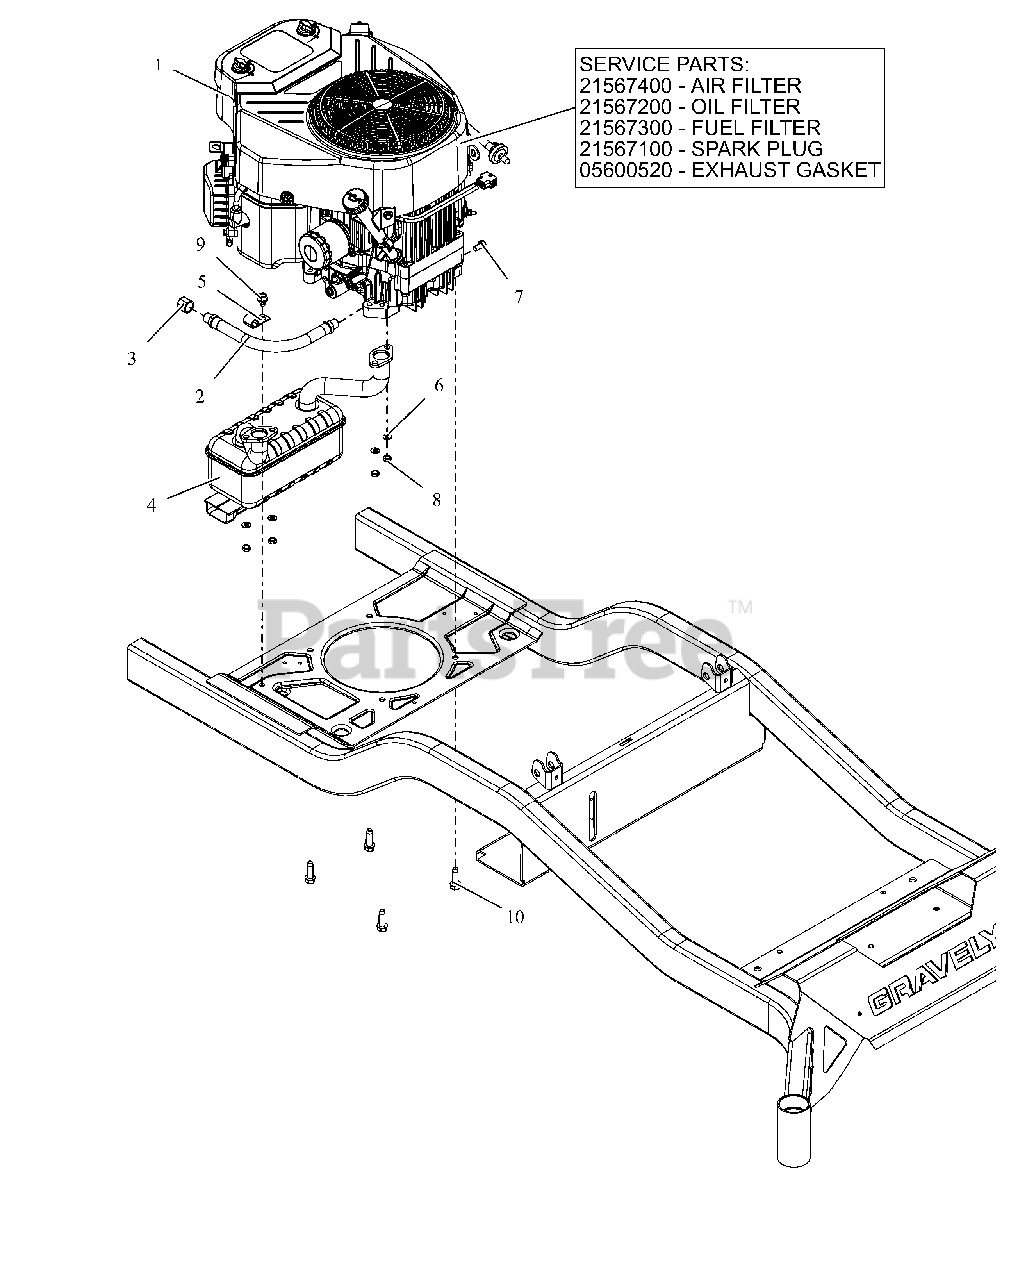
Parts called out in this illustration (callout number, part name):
1	ENGINE, LONCIN 764cc
1	FILTER, AIR
1	FILTER, OIL LONCIN
1	FILTER, FUEL
1	PLUG, SPARK
1	GASKET, MUFFLER LONCIN
2	HOSE,HYD .38-11-0K M6NO-M6N0
3	PIPE CAP 3/8 NPT FEMALE
4	MUFFLER,
6	WSHR,LK-REG .312X.078 ZCC
7	BLT, HEX .31-18X.625 G5 ZCC
8	NUT,NYL M8-1.25 G8.8 ZCC
9	SCR,TAP .375-16X.50 HWH TR ZCC
10	SCR,TAP .375-16X1.25HWH TR ZCC
